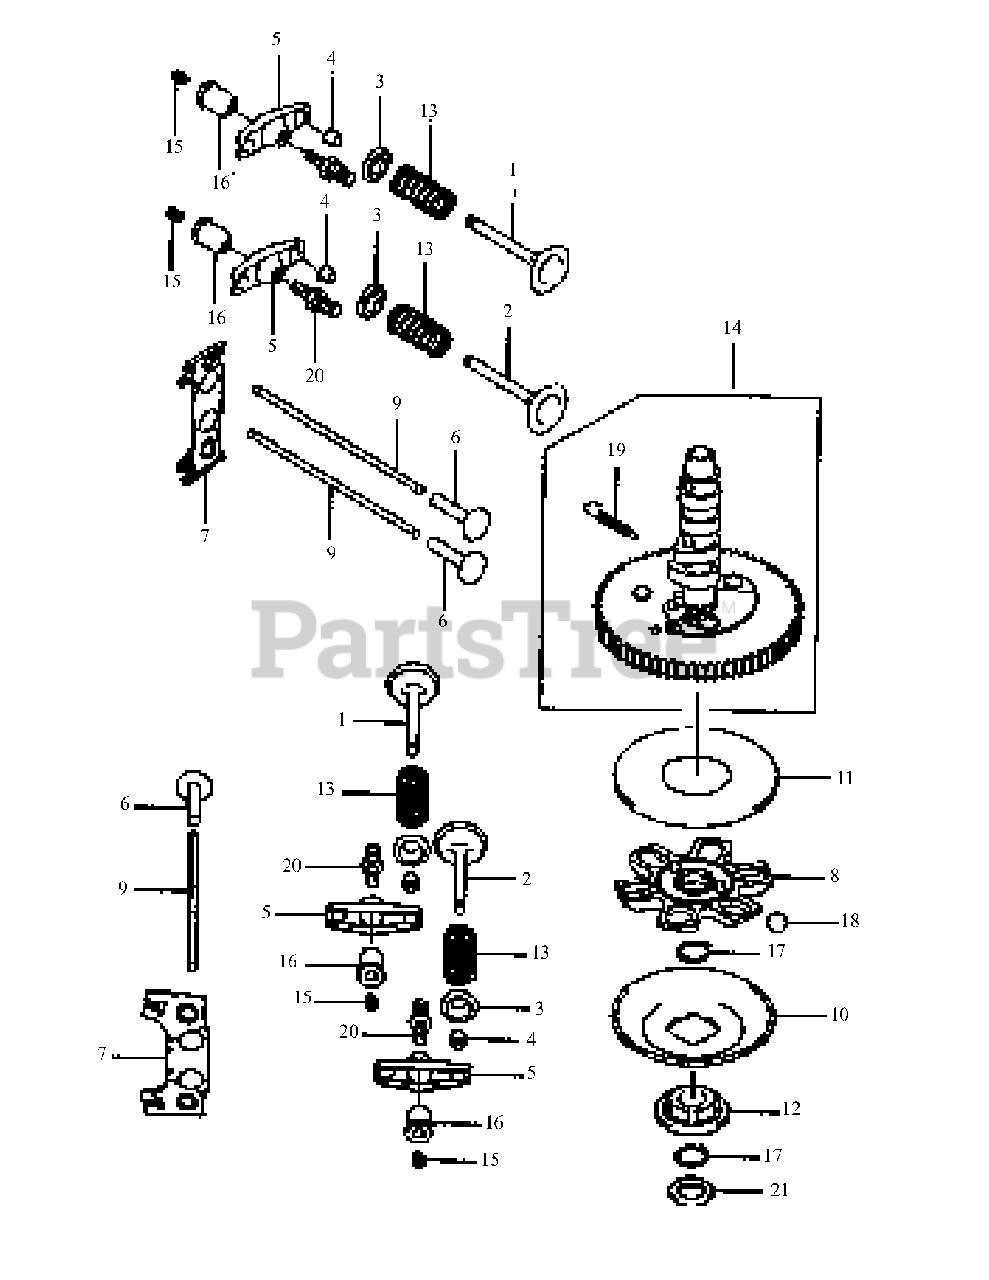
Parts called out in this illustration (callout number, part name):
2	Valve-Exhaust
3	Retainer, Valve Spring
7	Guide, Push Rod
13	Spring-Engine Valve
14	Camshaft-Complete
17	Ring-Snap
18	Ball
19	Spring
